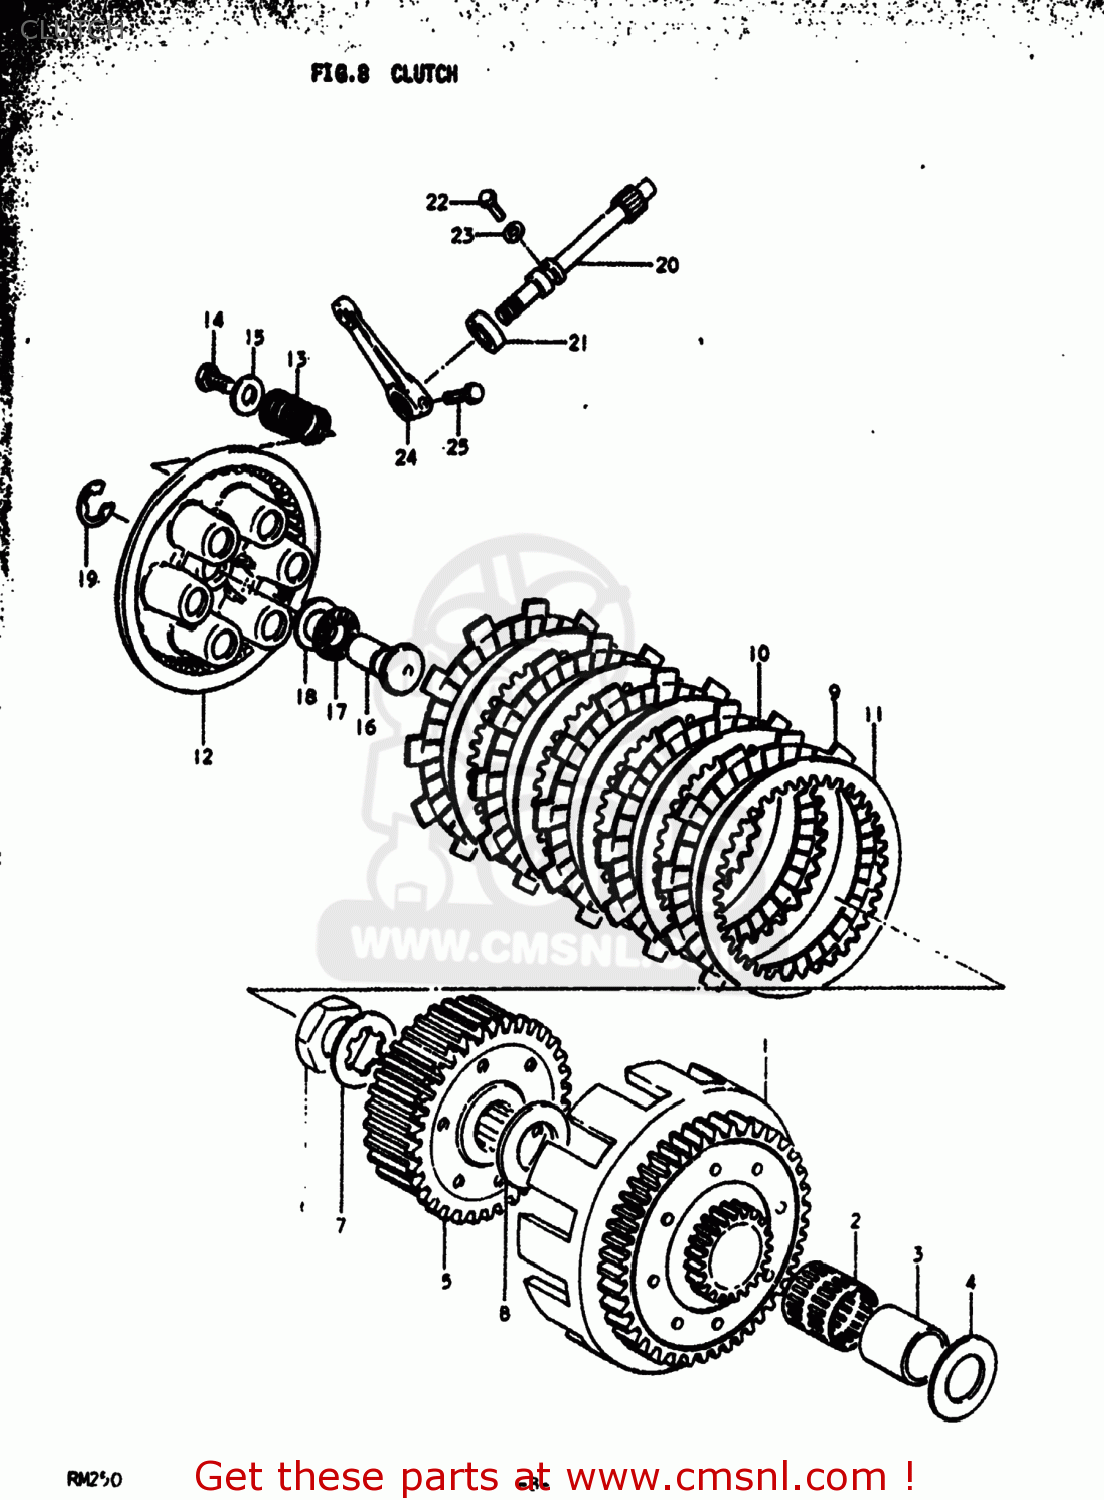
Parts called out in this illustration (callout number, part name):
1	GEAR ASSEMBLY,PRIMARY DRIVE
2	ROLLER BEARING (25X30X2
3	SPACER
4	WASHER(20X38X2)
5	HUB,CLUTCH SLEEVE
6	NUT (20MM)
7	WASHER,LOCK
8	WASHER(20X38X2)
9	PLATE,CLUTCH DRIVE (MCA)
10	PLATE,CLUTCH DRIVEN (NAS)
11	PLATE,CLUTCH DRIVEN(T:2.0) (NAS)
12	DISC,CLUTCH PRESSURE
13	SPRING
14	BOLT, UPPER
15	WASHER
16	RACK,CLUTCH RELEASE
17	BEARING(15X28X2)
18	WASHER
19	E RING 12MM
20	PINION,CLUTCH RELEASE
21	OIL SEAL
22	BOLT(6X12)
23	WASHER
24	ARM,CLUTCH RELEASE
25	BOLT
